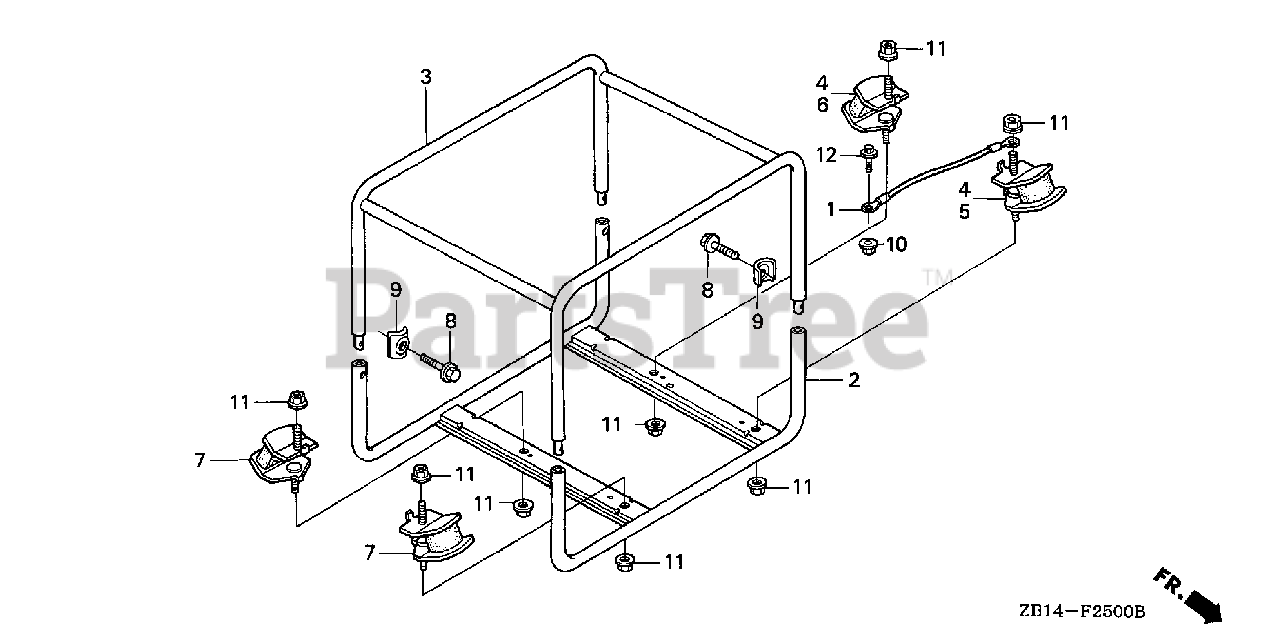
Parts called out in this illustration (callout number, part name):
1	CABLE, GROUND
2	FRAME (LOWER) (NOT AVAILABLE)
3	FRAME (UPPER)
4	RUBBER (LOWER)
7	RUBBER (LOWER)
8	BOLT, FLANGE (8X20) (NOT AVAILABLE)
8	BOLT, FLANGE (8X16)
8	BOLT, FLANGE (8X20)
9	WASHER, FRAME JOINT
10	NUT, FLANGE (6MM)
11	NUT, FLANGE (8MM)
12	BOLT, FLANGE (6X10)
